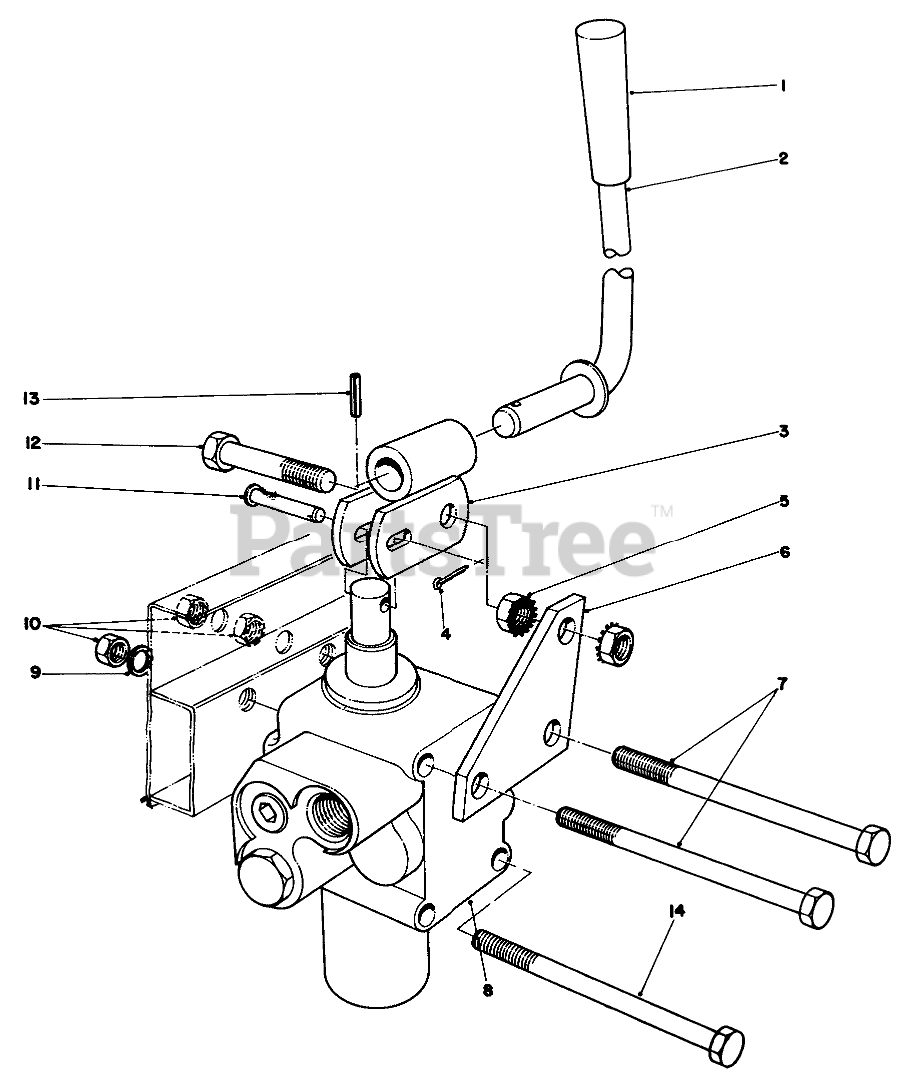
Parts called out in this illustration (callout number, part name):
1	KNOB-CONTROL
2	Lever-Valve
3	Valve Lever Link
4	PIN-COTTER
5	NUT-KEPS
6	Wheel Bolt
7	SCREW-HH
8	VALVE ASM
9	WASHER-LOCK
10	NUT-HEX
11	PIN-CLEVIS
12	SCREW-HH
13	PIN-ROLL
14	SCREW-HH
